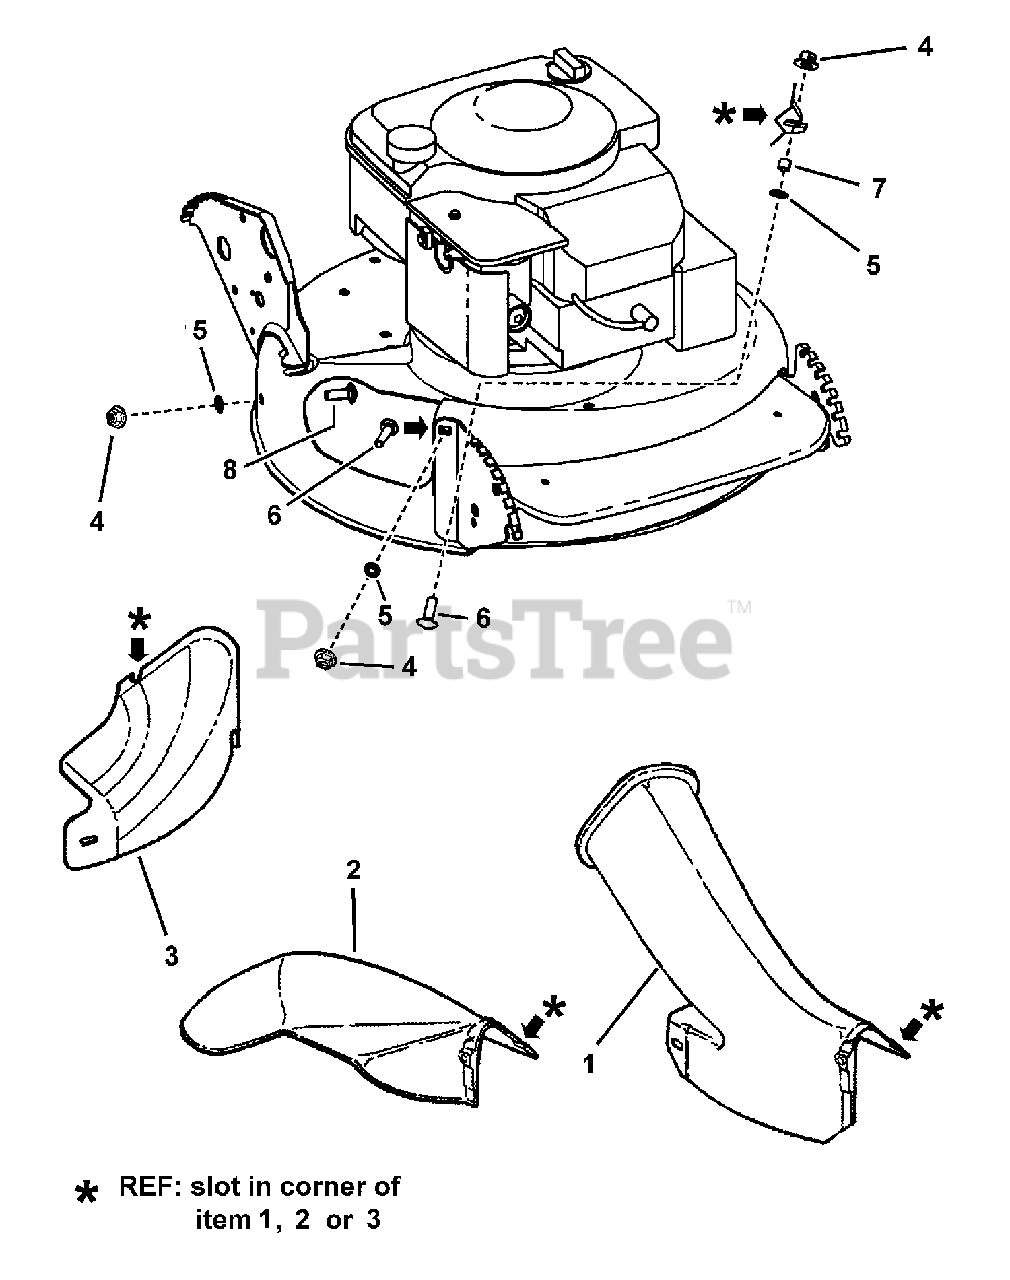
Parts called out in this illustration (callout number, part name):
1	ADAPTER, Grass Bag Euro 21"
2	SIDE CHUTE, 21"
3	COVER, 21" Deck
4	NUT, 5/16-18 Hex Large Flange Center Lock
5	RETAINER, 5/16" Bolt
6	BOLT, 5/16-18 x 1-1/8" Short Neck Carriage GR 5 ZP
7	SPACER, .316 I.D. x .375 O.D. x .310 thick
8	BOLT, 5/16-18 x 3/4" Short Neck Carriage GR 5
